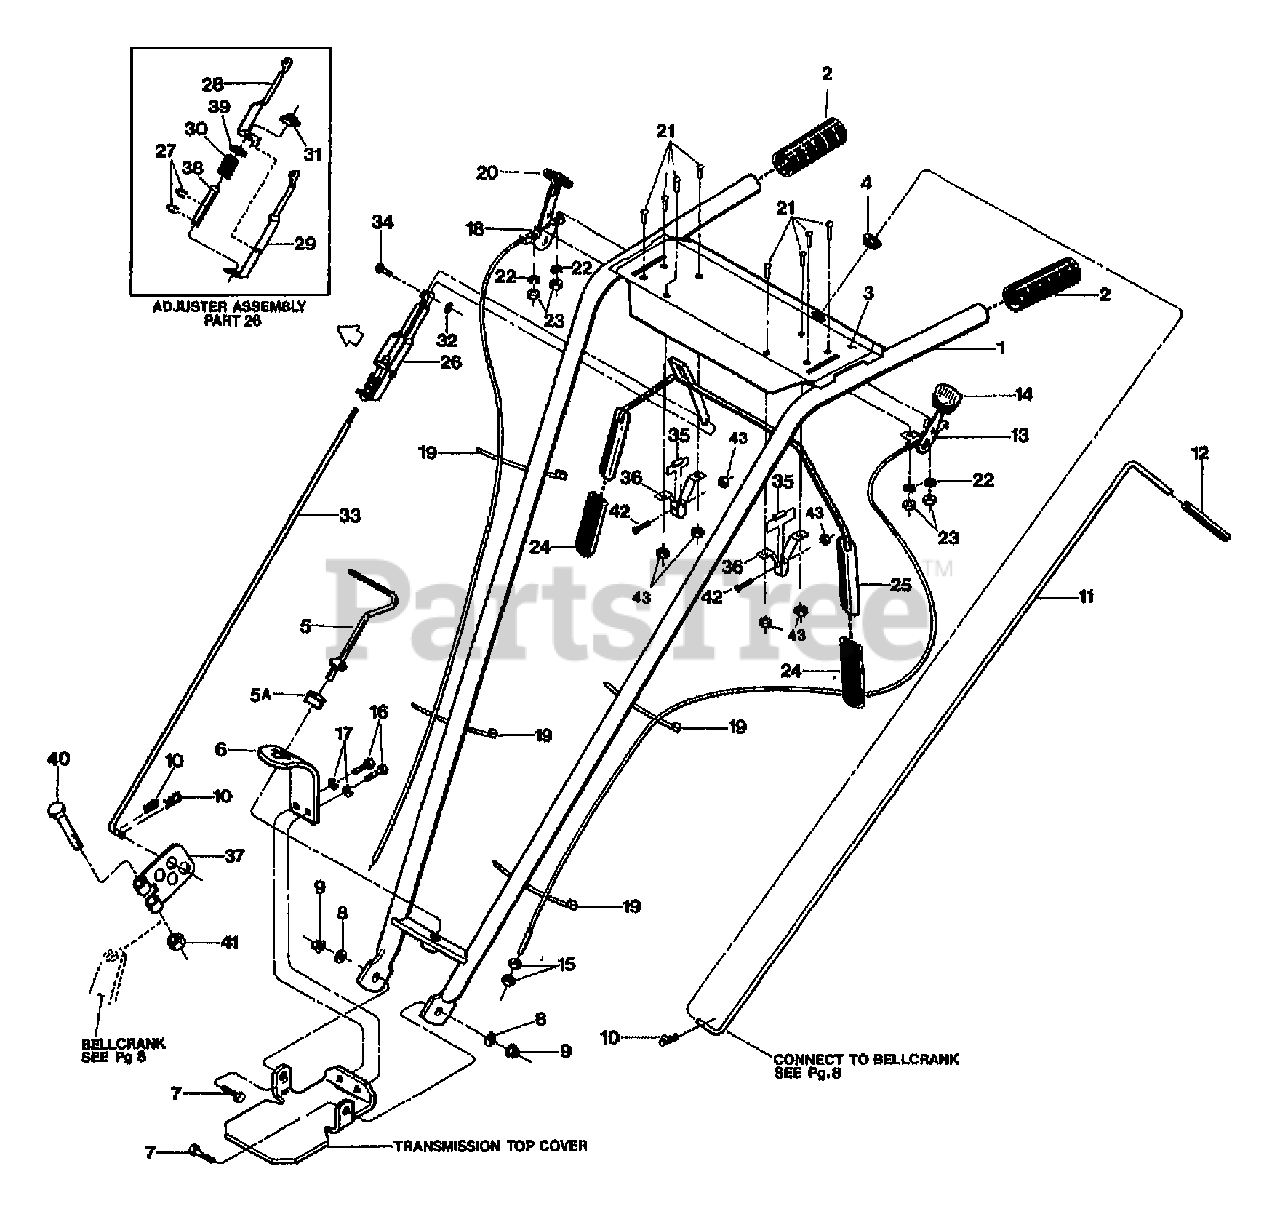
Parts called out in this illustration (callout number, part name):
1	ASSM-HANDLEBAR W/GRIPS (INCL. 2-5A)
2	GRIP-H/BAR SMOOTH
3	DECAL-CONTROL PANEL
4	BUSHING-NYLON (PART OF OPERATOR CONTROL PANEL)
5	ASSM-STUD H/B
5A	WASHER-1.0X.38X.375
6	PLATE-HANDLEBAR ADJUST
7	SCR-HH 3/8-16X1.0 G5 ZP
8	WASHER-FLAT 3/8 SAE
9	NUT-LOCK 3/8-16 NYLON ZP
10	PIN-CLIP .08
11	ROD-REV W/GRIP OPC (INCL. GRIP, #9198)
12	GRIP-CONTROL ROD
13	CABLE-WHEEL CLUTCH OPC (INCL. 14)
14	KNOB-WHEEL DRIVE CABLE
15	NUT-HEX 5/16-24
16	SCR-HH 3/8-16X.75 G5 ZP
17	WASHER-LK .375 @ DEPL
18	CABLE-THROTTLE ECONO OPC
19	TIE-RED (PLASTIC)
20	KNOB-THROTTLE CABLE
21	SCR-RH M10-32X.5 MACH
22	WASHER-LK M10
23	NUT-HH M10-32X.125
24	GRIP-PADDLE SM FRAME OPC
25	BAIL W/GRIPS OPC (WITH TWO GRIPS, #9390)
26	ASSM-ADJUSTMENT OPC (INCL. 27-30,38-39)
27	RING-KLIP .500 ZINC
28	ADJUSTER-RT SIDE OPC
29	ADJUSTER-LT SIDE OPC
30	SPRING-ADJUSTER OPC
31	WELDNUT 5/16-18
32	RING-KLIP .188 DIA
33	ROD-CONTROL OPC
34	ASSM-PIN & CLIP (SMALL FRAME)
35	SPACER-#10 SPLIT
36	BRACKET-BAIL OPC
38	BUSHING-.5X.334X2.88
39	WASHER-.75X.51X.06 ZP
40	SCR-HH 1/4-20X1.5 G5ZP
41	NUT-LK 1/4-20
42	SCR 10-32
43	NUT W/LKWASHER #10-32 ZP
